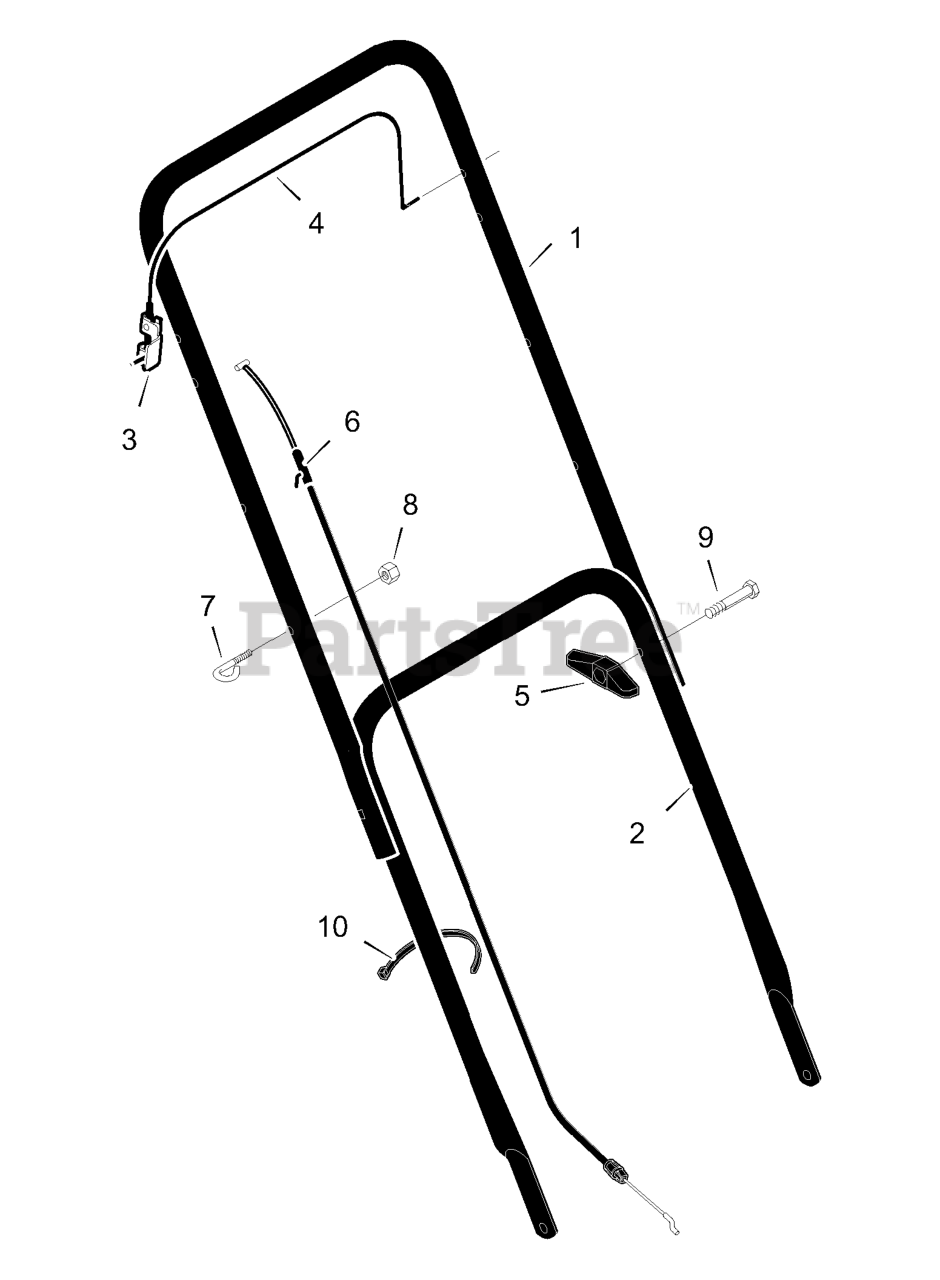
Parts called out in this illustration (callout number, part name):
1	Handle, Upper (Black)
2	Handle, Lower (Black)
3	Bracket, Stop Lever
4	Lever, Stop
5	Knob, Plastic
6	Engine Stop Cable
7	Guide, Rope
8	Locknut
10	Fastener, Cable
